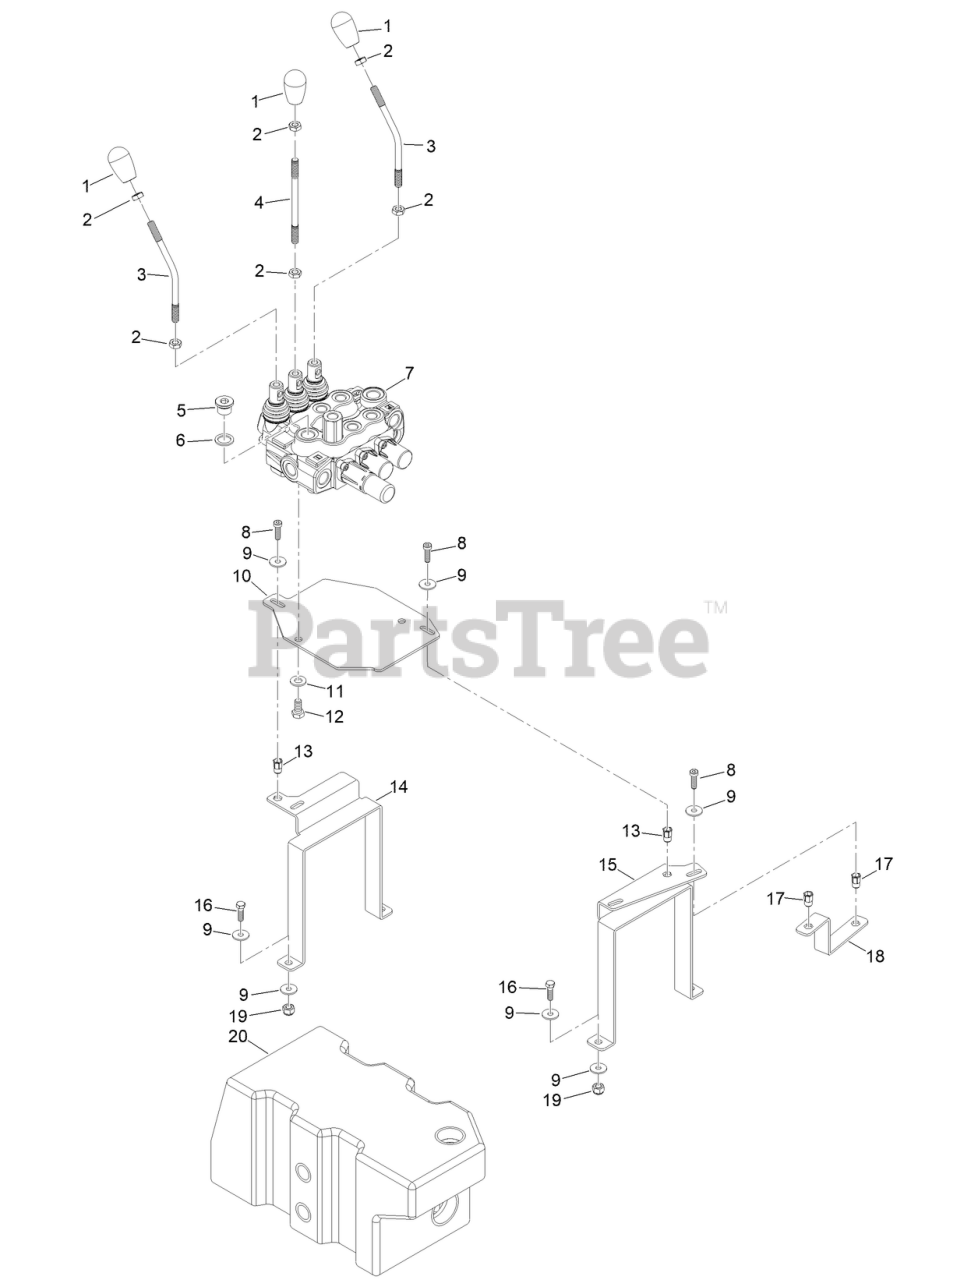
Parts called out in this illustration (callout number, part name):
6	SEAL - 3/8in
7	VALVE-LIFT
9	WASHER
10	PLATE, LIFT VALVE
11	WASHER
13	INSERT-THREADED
14	CLAMP-BAND
15	CLAMP-BAND
17	FITTING
18	SUPPORT, WATER EXPANSION TANK
20	TANK-OIL
